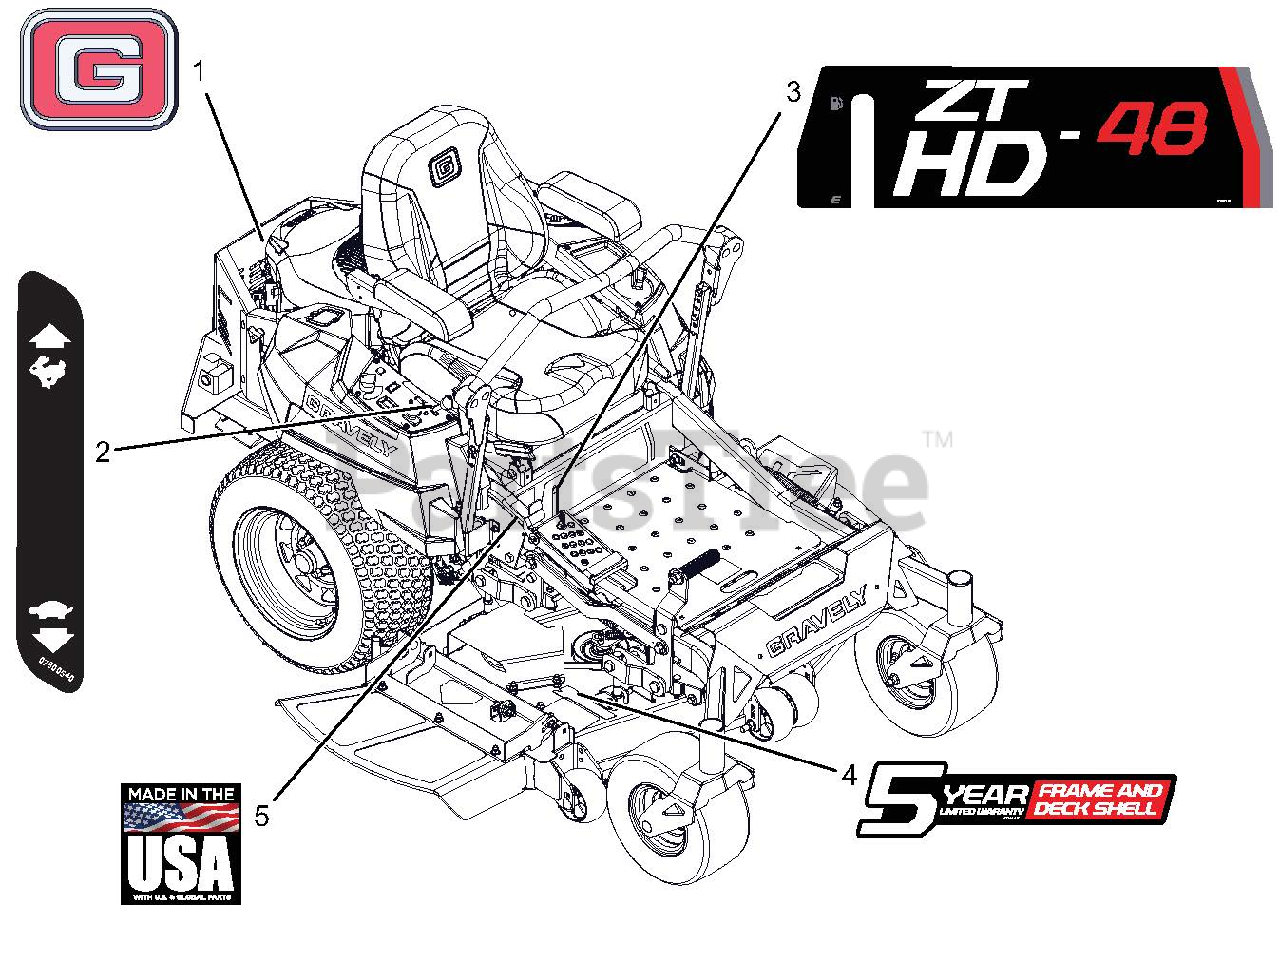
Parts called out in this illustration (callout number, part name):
1	DECAL, GRAVELY BRAND
2	DECAL, DASH DECAL
3	DECAL - 48HD
4	DECAL, DECK 5 YEAR-GRAVELY
5	DECAL, MADE IN USA
